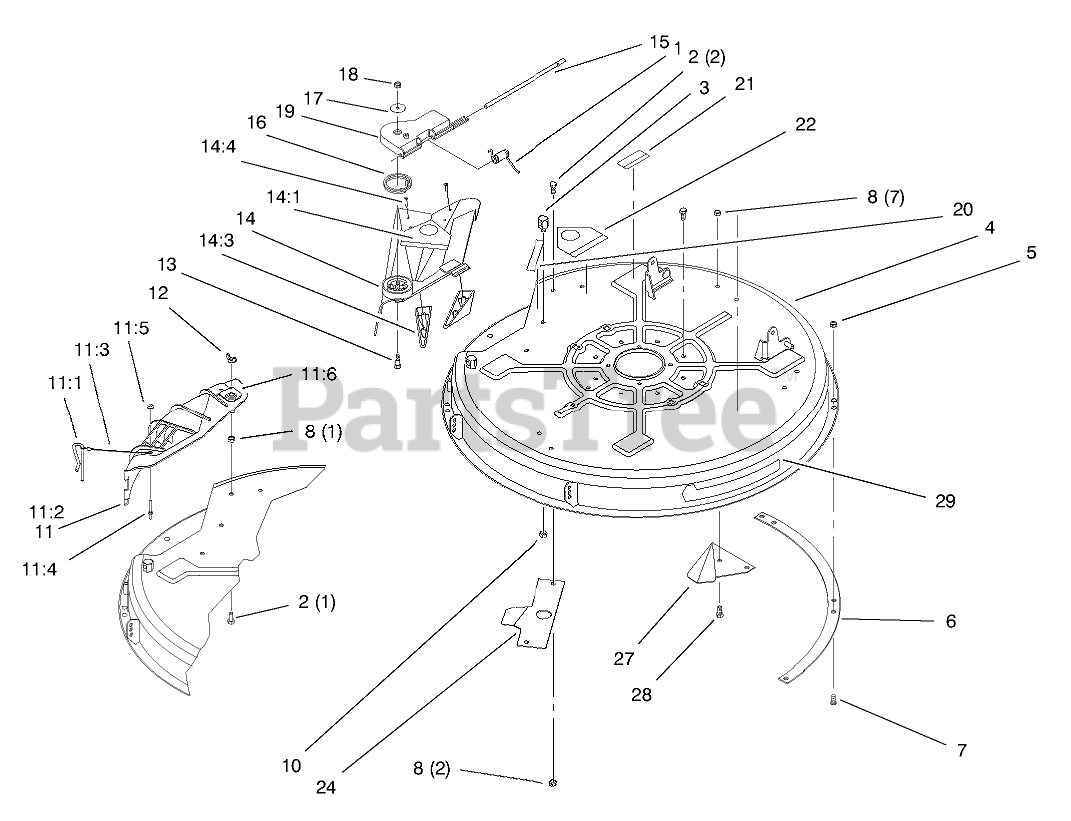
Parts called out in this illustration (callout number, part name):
1	SPRING-TORSION
2	SCREW-HH
3	POST-PIVOT
4	Deck Wa 32" Lt
4	DECK ASM
5	NUT-LOCK, NI
6	RING-DECK
7	SCREW-PPH
8	NUT-LOCK, NI
10	NUT-LOCK, NI
11	DISCHARGE COVER ASM
11:1	PIN-LOCKING, CHUTE
11:2	COVER-32" (W/KICKER)
11:3	LANYARD
11:4	RIVET-BLIND
11:5	WASHER-PLAIN
12	NUT-WING
13	BOLT-SHOULDER
14	32 INCH DEFLECTOR ASM
14:1	DECAL-DANGER
14:3	KICKER
14:4	SCREW-PPH
15	ROD-HINGE, DEFLECTOR
16	SPRING-TORSION
17	WASHER-FLAT
18	NUT-LOCK, NI
19	PIVOT-HINGE, DEFLECTOR
20	DECAL-DANGER
21	DECAL-WARNING
22	DECAL-DANGER
24	RAMP-DEFLECTOR
28	SCREW-HH
29	DECAL-RECYCLER
